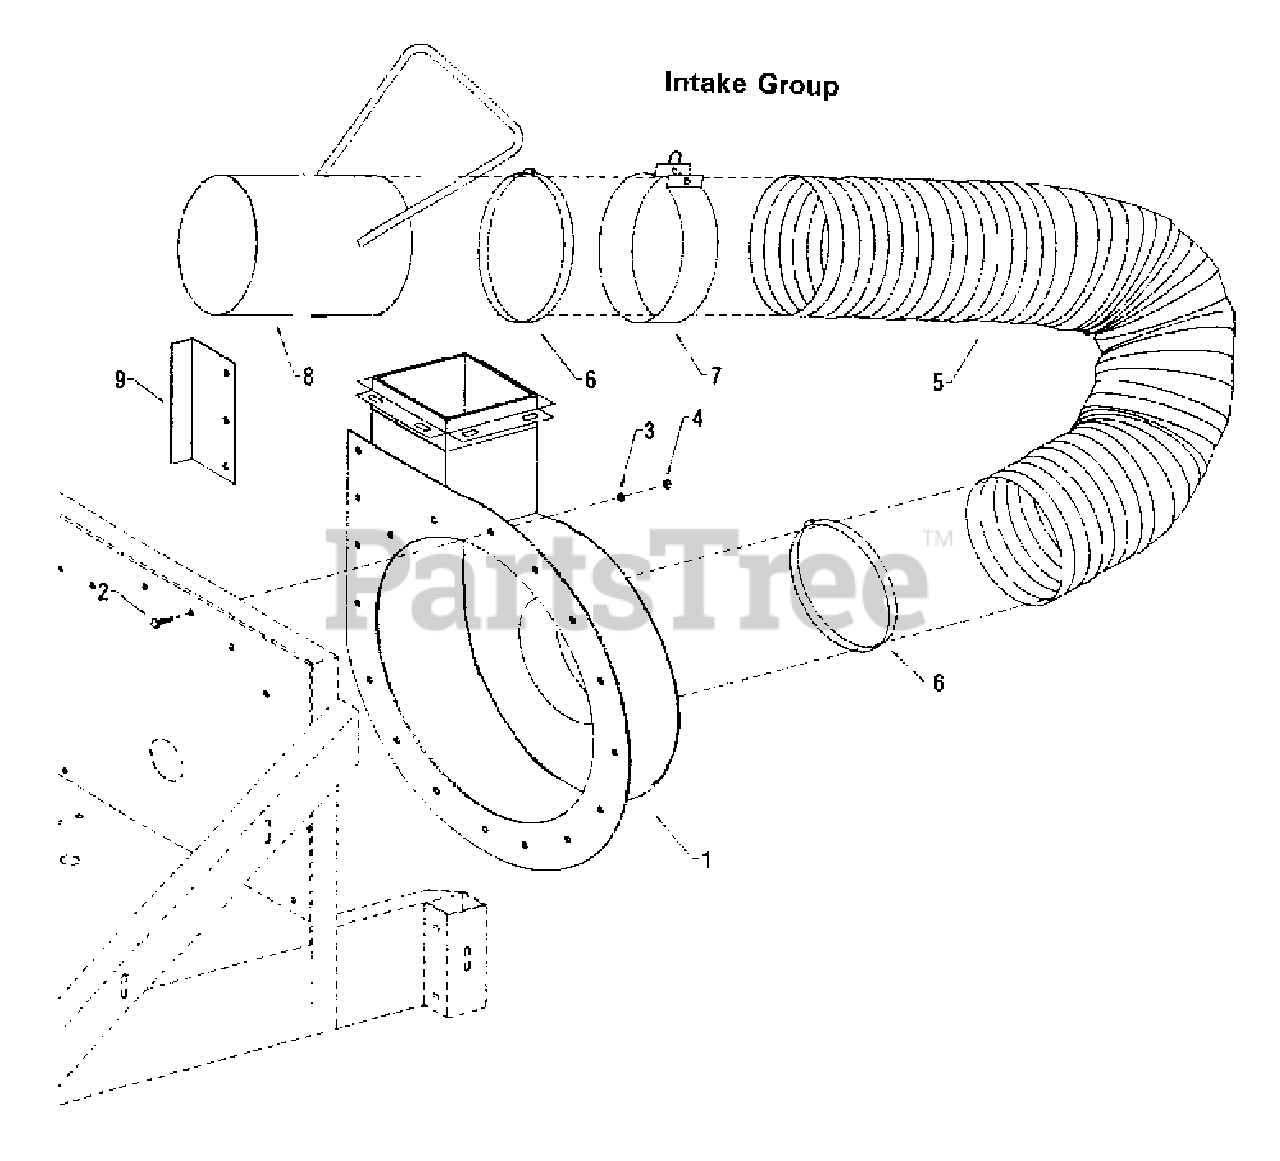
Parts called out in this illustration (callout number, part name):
1	Housing, Impeller - Complete with Liner Kit Below
2	3/8-16 x 1" Hex Bolt
3	3/8 Lock Washer
4	3/8-16 Hex Nut
5	Hose, Intake 12" x 10'
6	Clamp, Hose 12"
7	Band, Hose Support 12" with Hardware
8	Nozzle, Intake 12" w/Adjustable Handle
9	Plate, Hose Protector (CHW Units Only)
